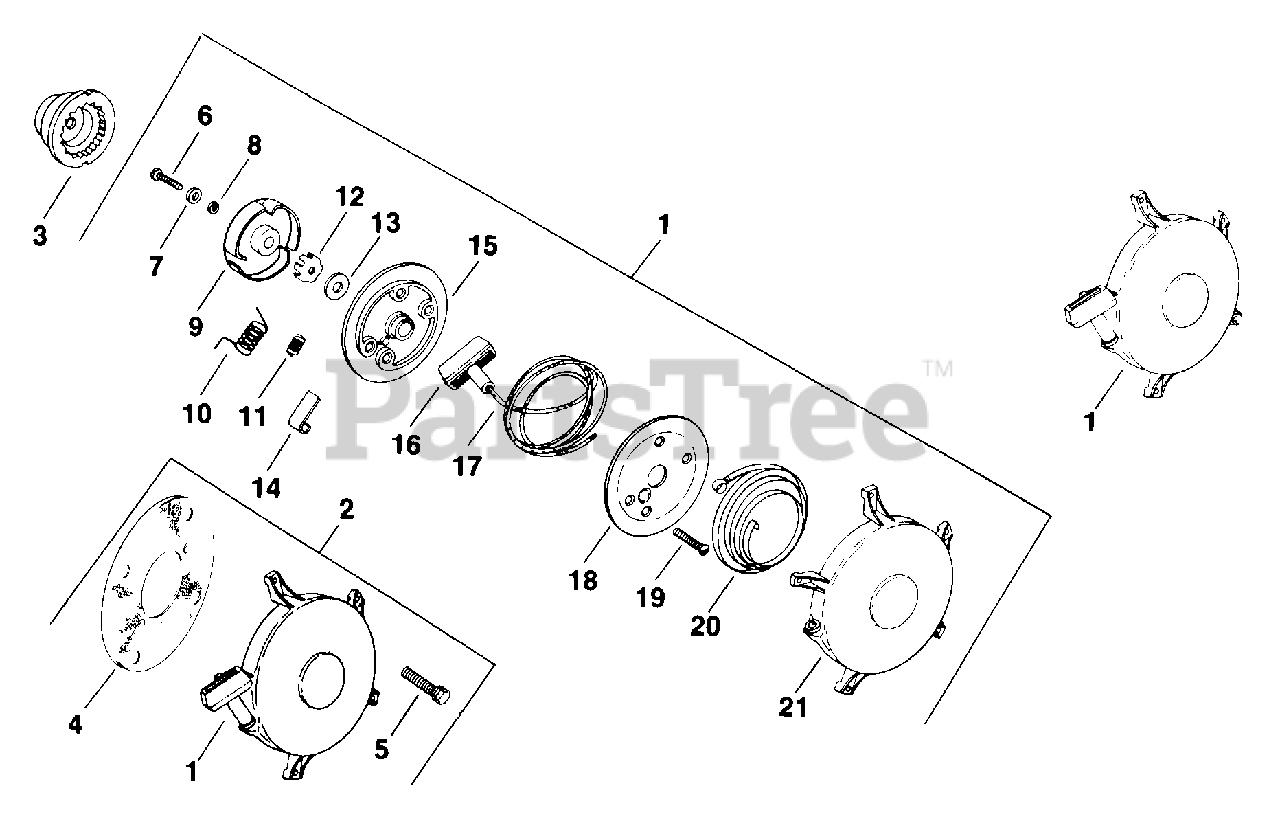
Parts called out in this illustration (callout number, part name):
1	STARTER
3	CUP, DRIVE - DISCONTINUED
7	WASHER - DISCONTINUED
9	RETAINER
11	SPRING - DISCONTINUED
14	DOGS - DISCONTINUED
16	HANDLE - USE 25 166 01
21	HOUSING - DISCONTINUED
